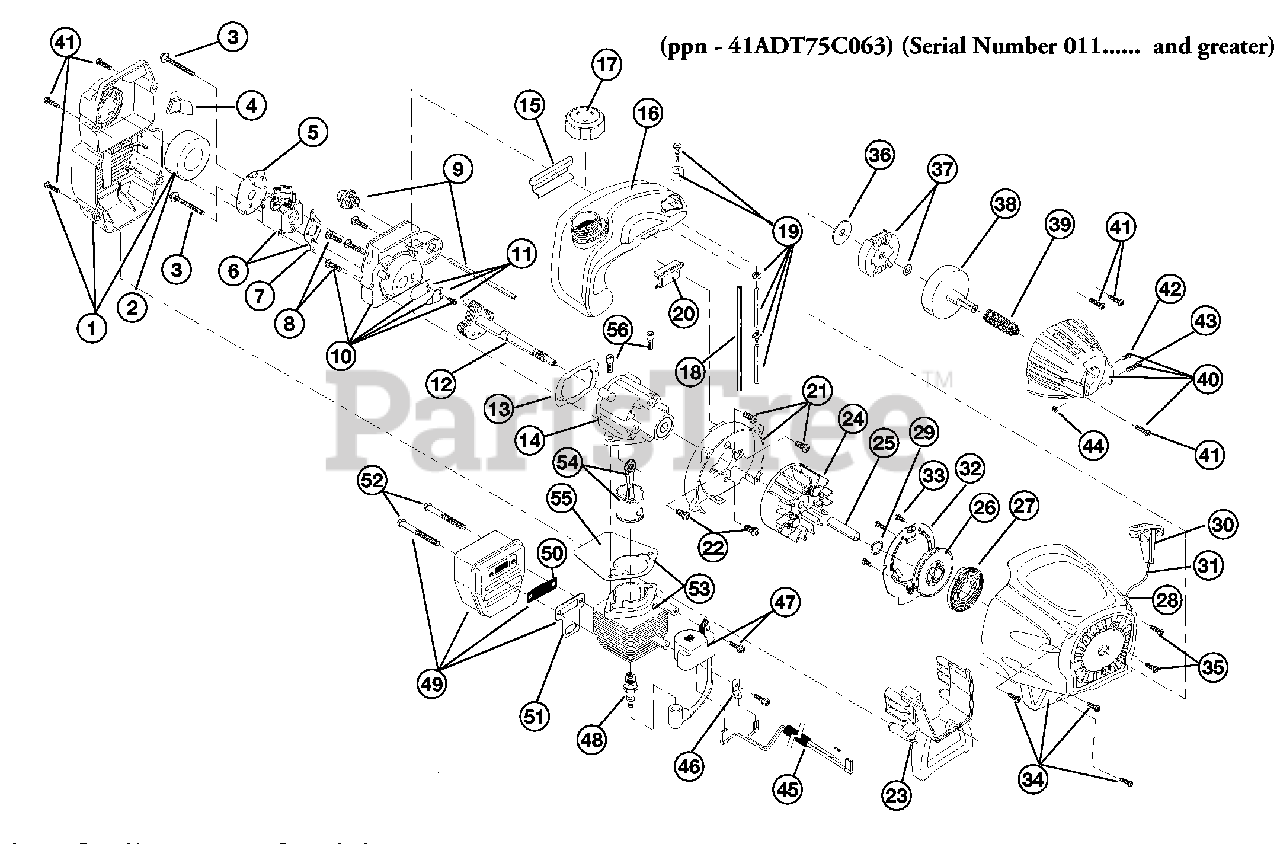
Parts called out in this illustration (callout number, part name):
1	Air Cleaner/Muffler Cover Assembly (includes 2 & 41)
2	Air Cleaner Filter
3	Carburetor Mounting Screw Assembly
4	Choke Extension
5	Choke Plate
6	Carburetor Assembly W/Limiter Caps (includes 7 & 18)
7	Carburetor Gasket
8	Carb Mount Screw
9	Primer and Hose Assembly
10	Carb Mount Assembly (includes 8)
11	Reed Assembly
12	Power Shaft Assembly
13	Carburetor Mount Gasket
14	Crank Case Service Assembly (includes 10, 12 & 22)
15	Rear Mounting Pad
16	Fuel Tank Assembly (includes 17-19)
17	Fuel Cap Assembly
18	Fuel Return Line
19	Fuel Line Assembly
20	Front Mounting Pad
21	Shroud Assembly
22	Shroud Screw
23	Shroud Extension and Stand
24	Flywheel Assembly
26	Recoil Pulley Assembly
27	Recoil Spring
28	Rope Guide
29	Pulley Retainer
30	Pull Handle
32	Pressure Plate Assembly
33	Plate Screw
34	Starter Housing Assembly (includes 26-31 & 41)
35	Housing Screw
36	Clutch Washer
37	Clutch Rotor Assembly
38	Clutch Drum Assembly
40	Clutch Cover Assembly (includes 41-44)
41	Cover Screw
42	Anti-Rotation Screw
43	Clamping Screw
44	Clamping Nut
45	Wire Leads and Sleeve
46	Ground Tab
47	Module Assembly
49	Muffler Assembly (includes 50-52)
50	Spark Arrestor Screen
51	Exhaust Gasket
52	Muffler Mounting Bolt Assembly
53	Cylinder Assembly (includes 55)
54	Piston and Rod Assembly
55	Cylinder Gasket
56	Cylinder Bolt
